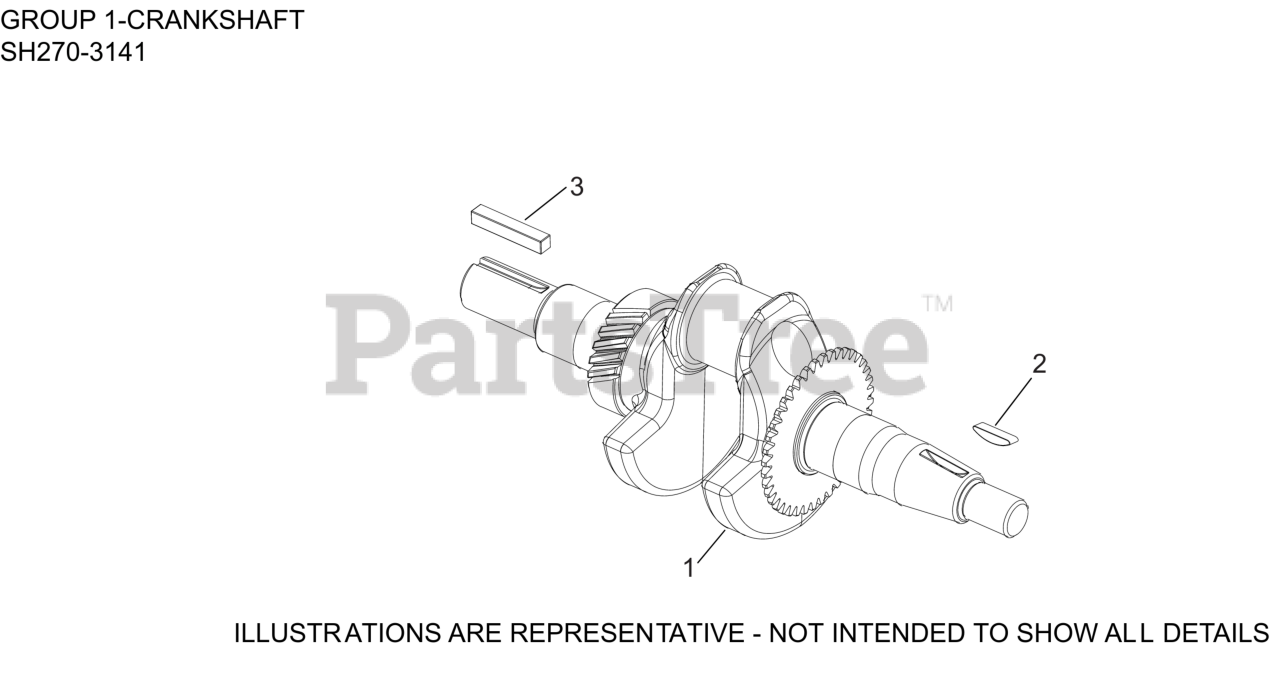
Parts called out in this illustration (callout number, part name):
1	CRANKSHAFT, ASSEMBLY
2	KEY, FLYWHEEL
3	KEY, SQUARE
